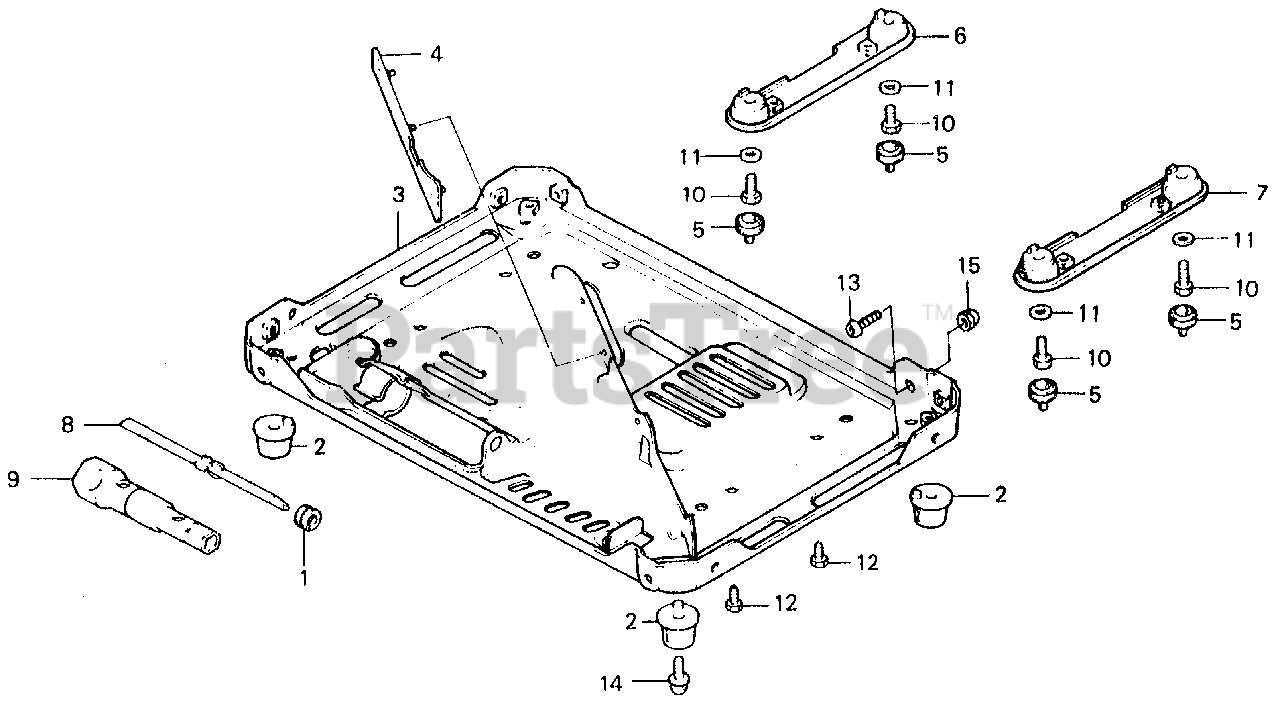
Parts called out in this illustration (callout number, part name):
1	GROMMET, THROTTLE CABLE (NOT AVAILABLE)
2	RUBBER (LOWER)
3	COVER (LOWER) *NH105* (MAT BLACK)
4	RUBBER, SEALED
5	RUBBER, SETTING STOPPER (NOT AVAILABLE)
6	FRAME, ENGINE
7	FRAME, ALTERNATOR
9	WRENCH, BOX (P19X10) (NOT AVAILABLE)
10	BOLT, HEX. (6X12)
11	WASHER (6MM)
12	BOLT, HEX. (5X10)
13	SCREW, PAN (6X8)
14	SCREW-WASHER (5X10)
15	NUT, CAP (6MM)
